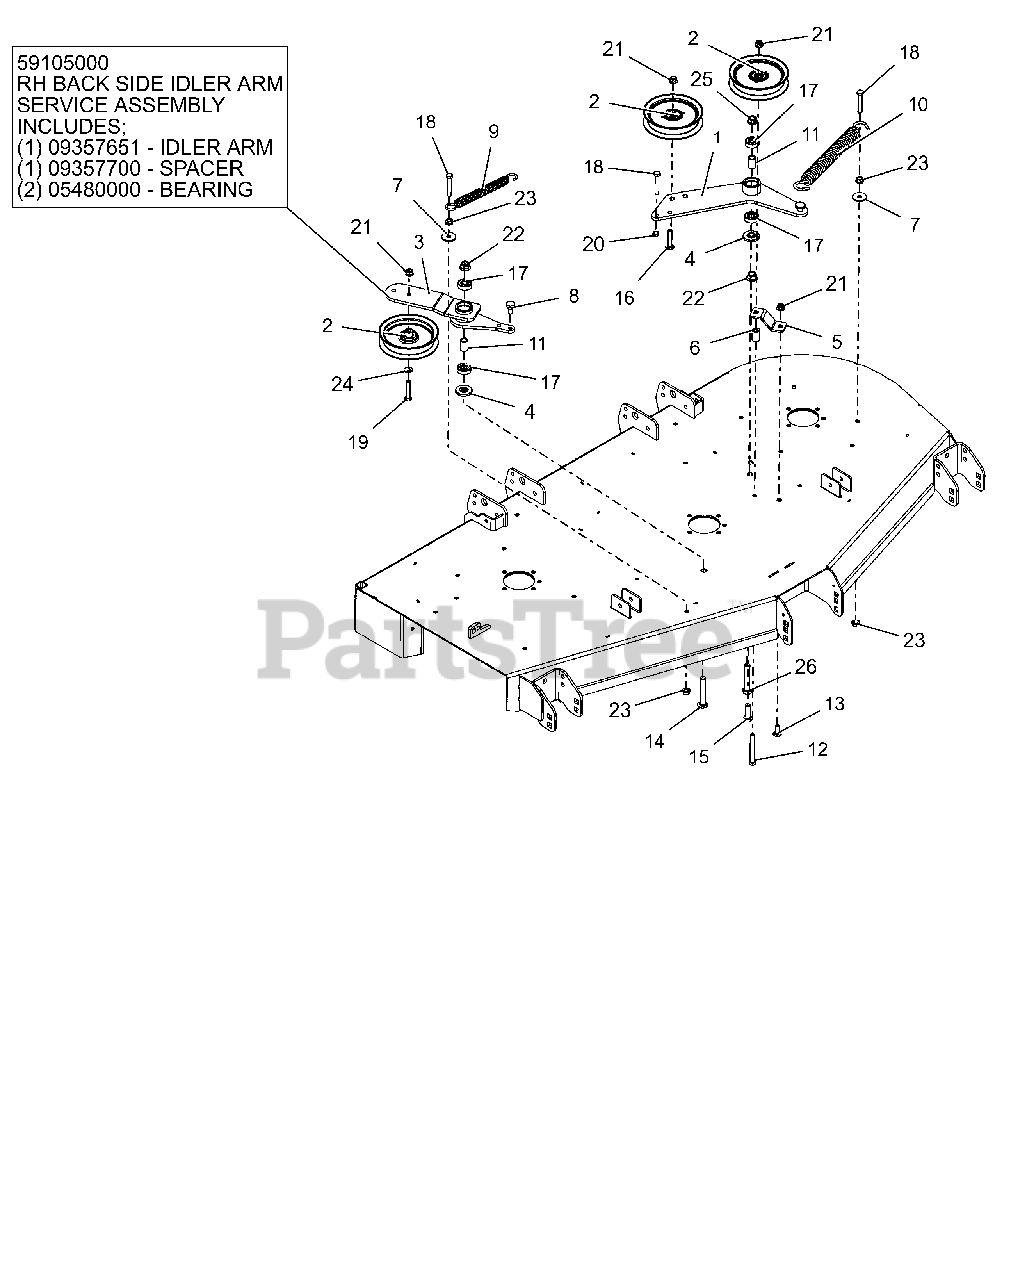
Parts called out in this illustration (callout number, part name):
1	DECK PTO IDLER ARM WLDMT - BLK
2	IDLER, FLAT 5.00"
3	DECK RH IDLER ARM WMT - BLK
3	RH BACKSIDE IDLER ARM ASSEMBLY
4	SPACER, IDLER ARM
5	PTO FIXED IDLER MTG BRKT -RED
6	BUSHING, SLV .380X.750X1.190
7	WSHR-FL-STL .406X1.375X.135 YZ
8	BLT,SHLDR EP .38-16X.30 HEX YZ
9	SPRING, EXTENSION
10	SPRING, EXTENSION
11	SPACER .510 X .75 X 1.1485
12	@BLT-HEX .38-16X3.25 GR5 YWZC
13	@BLT-RDHDSHSQNK.38-16X1.0 G5YZ
14	BLT,RDHDSQSHNK.50-13X3.25 G5YZ
15	@BLT-HEX .50-13X1.50 GR5 YWZC
16	BLT-RDHDSQNK .38-16X2.00 SHTYW
17	BRG-BALL .500X1.38X.437
18	@BLT-HEX .38-16X2.25 GR5 YWZC
19	@BLT-HEX .38-16X2.00 GR5 YWZC
20	NUT-HEX-JAM .375-16 YWZC
21	@NUT-LK-NYL-FLG .38-16 YWZC
22	@NUT-LK-NYL-FLG .50-13 YWZC
23	@NUT-SPNLK-FLG .375-16 YWZC
24	@WSHR-FL-STL.406X.812X.065 YWZ
25	NUT-LK-CTR-FLG .50-13 YWZC
26	@BLT-HEX .50-13X3.00 GR5 YWZC
